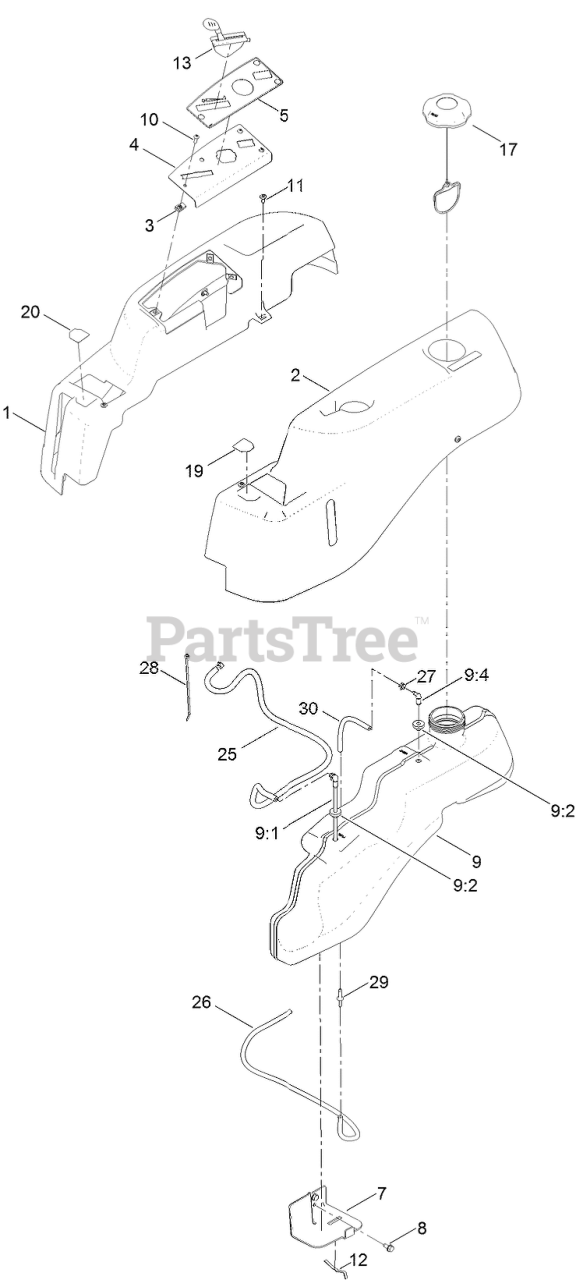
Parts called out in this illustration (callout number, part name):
1	POD-RH
2	POD-LH
4	PLATE-CONTROL
5	DECAL-PANEL, CONTROL
7	SUPPORT-TANK, FRONT
8	SCREW-HWHTF
9	FUEL TANK ASM
9:1	CONNECTOR-ELBOW, 90 DEG
9:2	BUSHING
9:4	FITTING-PLASTIC
10	SCREW-PRH
11	SCREW-SHOULDER
12	SPRING
13	CABLE-THROTTLE AND CHOKE
17	CAP-FUEL, RATCHETING
19	DECAL-LEVER, CONTROL (LH)
20	DECAL-LEVER, CONTROL (RH)
25	HOSE-FUEL
26	HOSE-FUEL
27	CLAMP-HOSE
28	TIE-CABLE
29	ADAPTOR-ORIFICE
30	HOSE-FUEL
